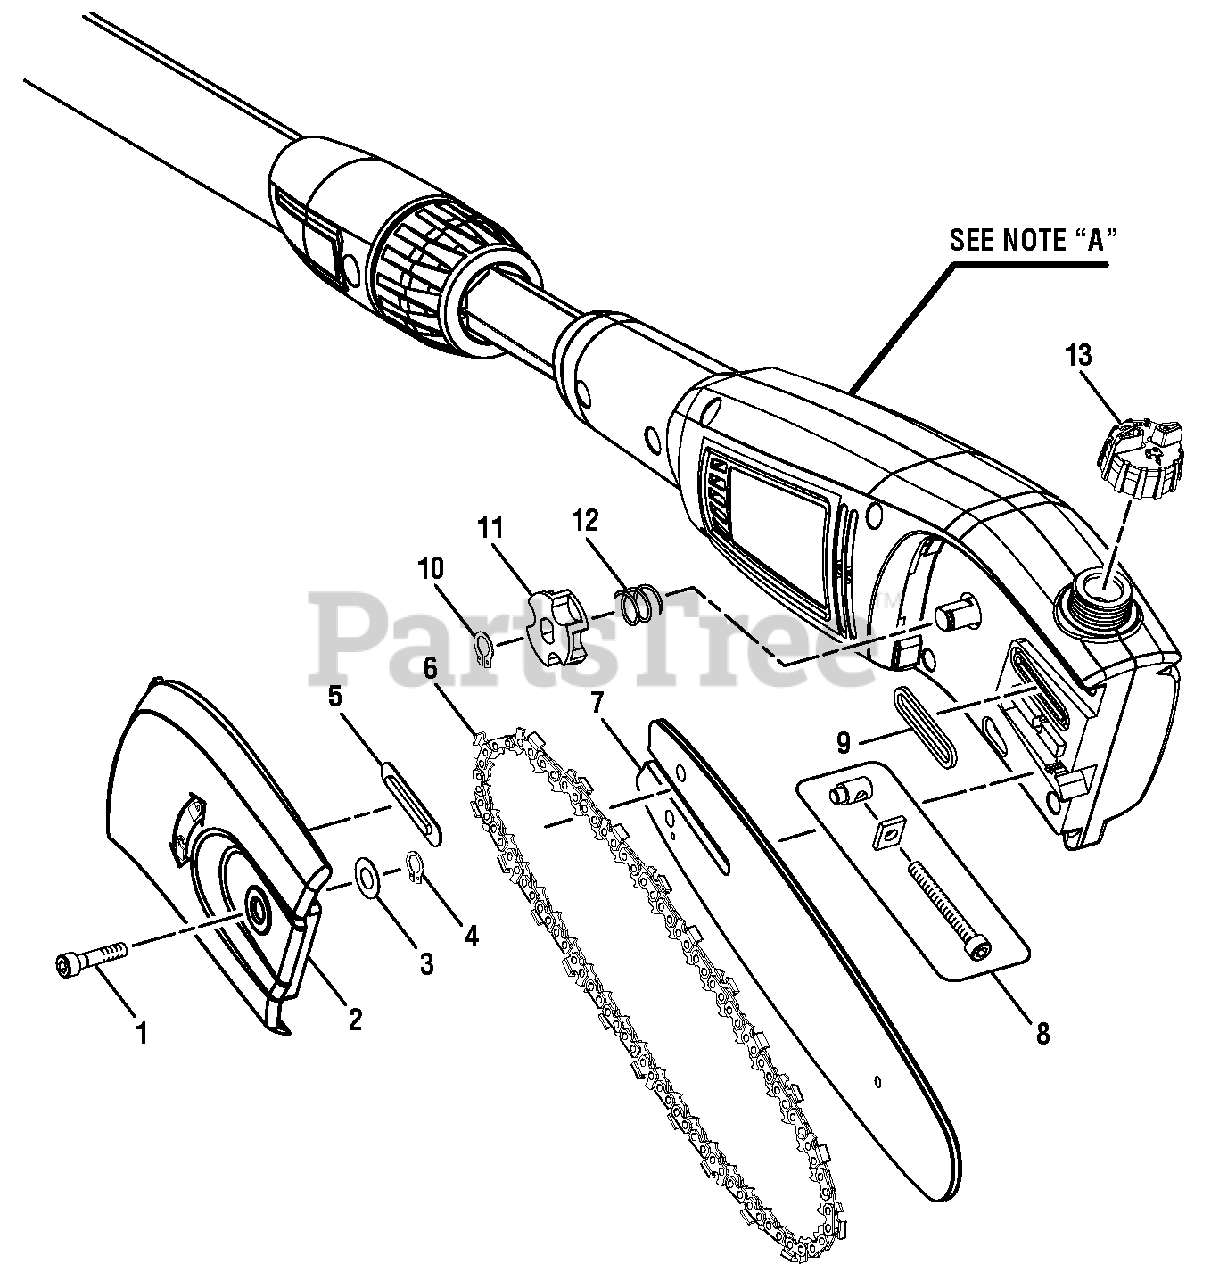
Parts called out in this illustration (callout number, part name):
2	Chain Cover Assembly
3	External Washer
4	Retaining Ring
5	Chain Cover Seal Ring
8	Chain Adjustment Assembly
9	Oil Outlet Seal Ring
10	Retaining Ring
12	Tension Spring
